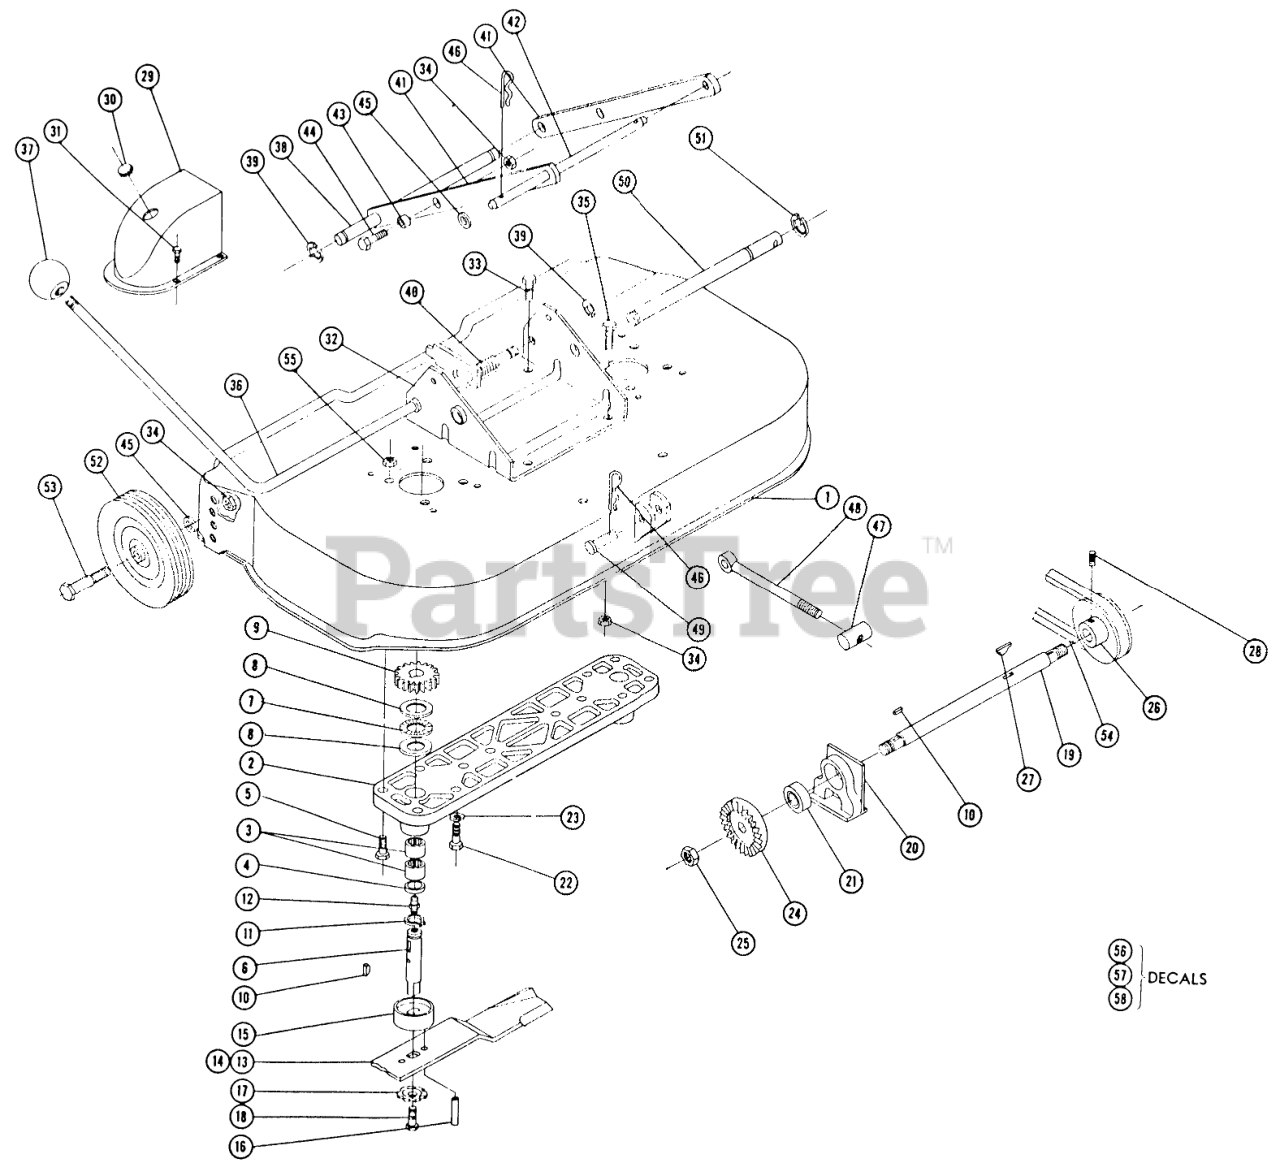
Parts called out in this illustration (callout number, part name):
1	Ass-y. Deck
5	Bolt 5/16-18 x
8	WASHER-THRUST
16	SPIROL ROLL PIN
18	Bolt 3/8-16 x 7/8
20	BEARING SUPPORT
22	Bolt 3/8-16 x 1
23	Lockwasher
25	Nut Hex 5/8-18 Thin
28	Set Screw 5/16-18 x 5/16
30	PLUG BUTTON
31	SCREW
32	Hanger
33	Bolt 3/8-16 x 3/4
34	3/8-16 E.S.
35	Bolt 3/8-16 x 1
36	Ass-y. Lift Lever
40	Spring-Torsion
41	Link-Rear Parallel
44	Bolt 3/8-16 x 7/8
45	Washer
46	Hairpin Cotter
49	Pin-Clevis
50	Shaft-Belt Tightener
51	E-RING
54	V BELT
55	Nut-Nylok
56	Decal
58	Decal-Belt Diagram
